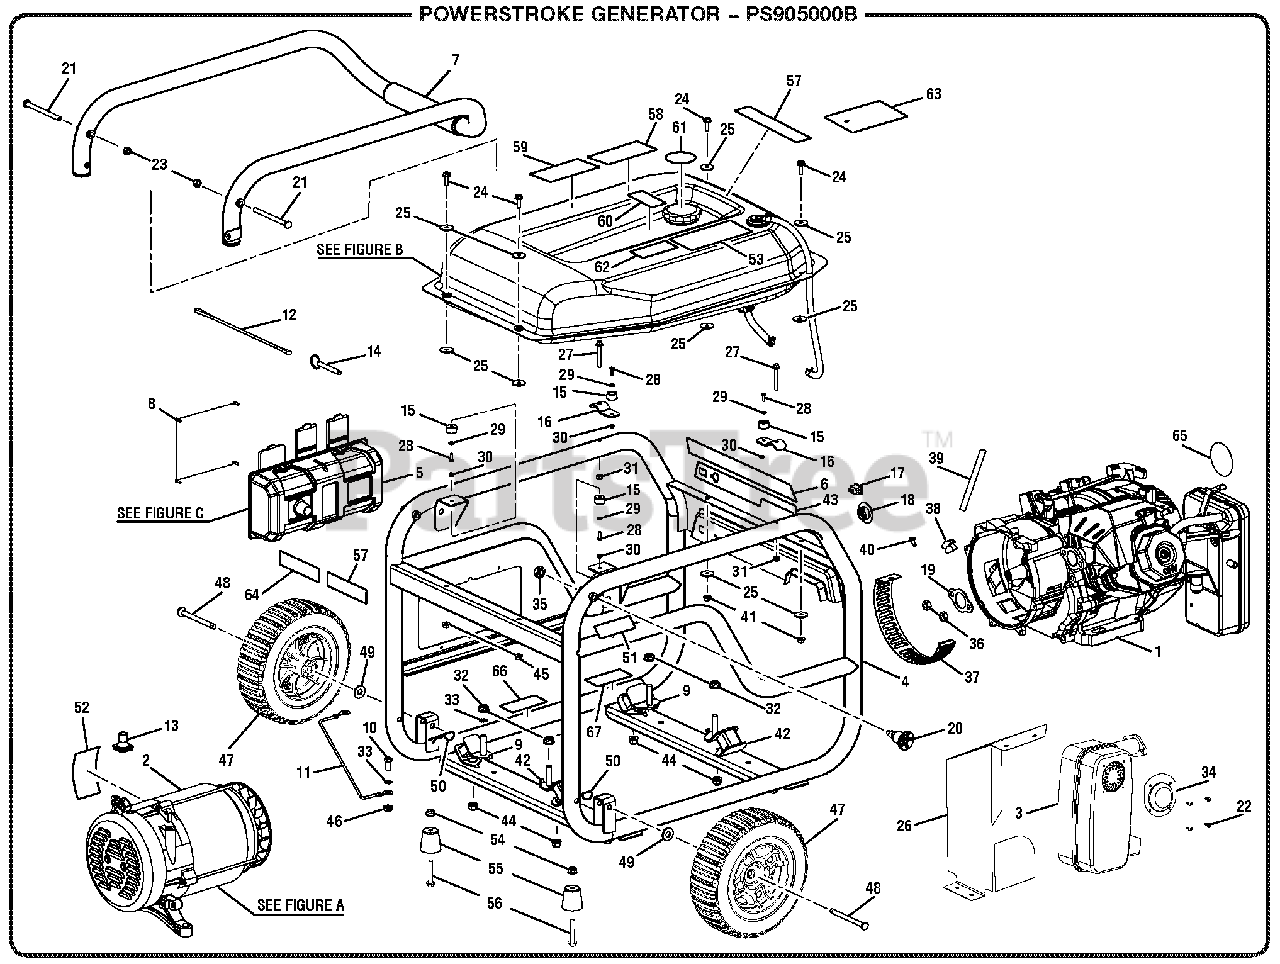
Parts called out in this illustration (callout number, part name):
2	Generator Head Assembly (See Fig. A)
4	Frame Assembly
5	Control Panel Assembly (See Fig. C)
6	Logo Label
7	Handle Assembly
8	Screw (6-20 x 3/8 in.)
9	Engine Isolator (Right)
10	Bolt (5/16-18 x 3/4 in.)
11	Ground Wire Assembly
13	Rubber Sleeve
14	Release Pin
15	Handle Bumper
16	Handle Support Bracket
17	On/Off Switch
18	Fuel Valve Bezel
19	Muffler Gasket
20	Handle Release Pin
21	Pivot Pin (Handle)
22	Screw (8-32 x 3/8 in.)
23	Lock Nut (5/16-18)
24	Bolt (M6 x 20 mm, Hex Washer Hd.)
25	Washer (M6)
26	Heat Shield
27	Bolt (M6 x 45 mm)
28	Bolt (M4 x 12.5 mm, Hex Hd.)
29	Washer (M4)
30	Lock Nut (M4)
31	Lock Nut (M6)
32	Lock Nut (5/16-18)
33	Star Washer (5/16 in.)
34	Spark Arrestor
35	Lock Nut (1/2-20)
36	Hex Nut (M8)
37	Fan Cover (Generator Head)
38	Plug (Generator Head)
39	Heat Shrink Tube
40	Screw (M5 x 10 mm, Hex Hd.)
41	Flange Nut (M6)
42	Engine Isolator (Left)
43	Start Label
44	Lock Nut (M8)
45	Hex Nut (1/4-20)
46	Hex Nut (5/16-18)
48	Axle Bolt
49	Washer (M10)
50	Hitch Pin
51	Hot Surface Label
52	Data Label (2013)
53	Danger Label
54	Lock Nut (M8)
55	Foot Assembly
56	Bolt (M8 x 1-1/4)
57	Fire Distance Label (Eng/Sp)
58	CPSC Label
59	Fire Danger Label
60	E85 Label
61	Fuel Stabilizer Label
62	Combustion Label (Eng/Sp)
63	Warning Hangtag
64	Ground Warning Label
65	Recoil Housing Label
66	Lubricant Label
67	Inquires label
